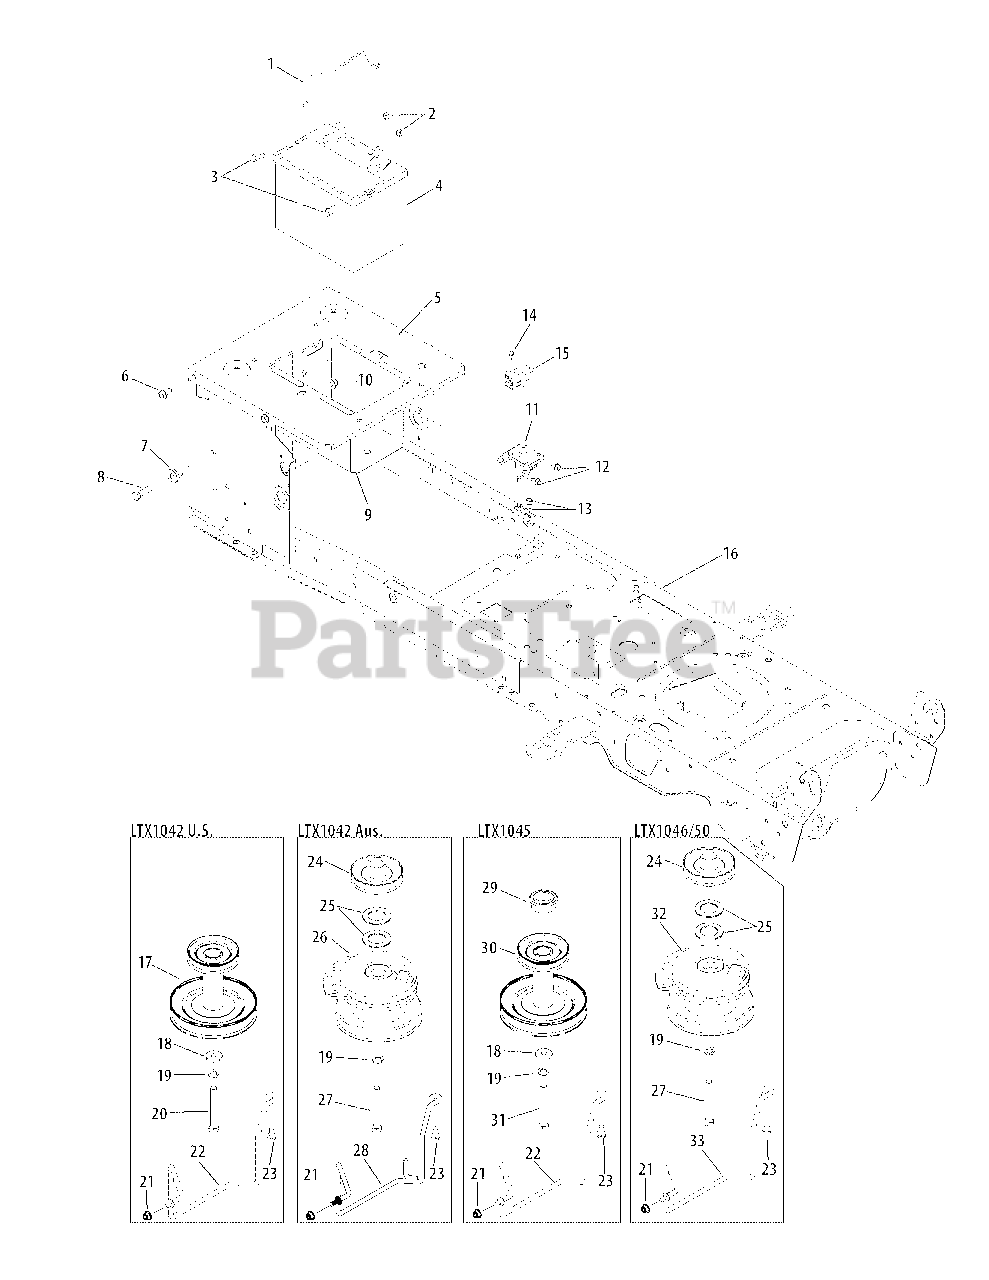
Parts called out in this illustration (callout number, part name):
1	Battery Hold-Down Rod
2	Sems Nut, 1.4-20
3	Hex Flange, 1.4-20 x .75
5	Seat Frame Bracket
6	Hex Washer Screw, 5.16-18 x .750
7	Shoulder Spacer, .38 x 1.0 x .70
8	Hex Screw, 3.8-16 x 1.25
10	Flange Lock Nut, 3.8-16
11	Solenoid
12	Hex Washer Screw, 1.4-20 x .375
13	Flange Lock Nut, 1.4-20
14	Shoulder Screw, #10-32 x .500
15	Interlock Switch
16	Lower Frame Assembly
17	Engine Pulley (LTX1042)
18	Flat Washer, .450 x 1.250 x .164 (LTX1042/1045)
19	Lock Washer, 7.16
20	Hex Screw, 7.16-20 x 2.75
21	Flange Lock Nut, 5.16-18
22	Keeper Rod (LTX1042/1045/1046)
23	Hex Washer Screw, 5.16-18 x .750
24	Engine Pulley (LTX1046/1050)
25	Flat Washer, 1.031 x 1.620 x .095 (LTX1046/1050)
26	Electric PTO Clutch
27	Hex Screw, 7.16-20 x 3.50 (LTX1046/1050)
28	Keeper Rod
29	Spacer, 1.010 x 1.400 x .825 (LTX1045)
30	Engine Pulley (LTX1045)
31	Hex Screw, 7.16-20 x 3.50 (LTX1045)
32	Electric PTO Clutch (LTX1046)
32	Electric PTO Clutch (LTX1050)
33	Keeper Rod (LTX1050)
